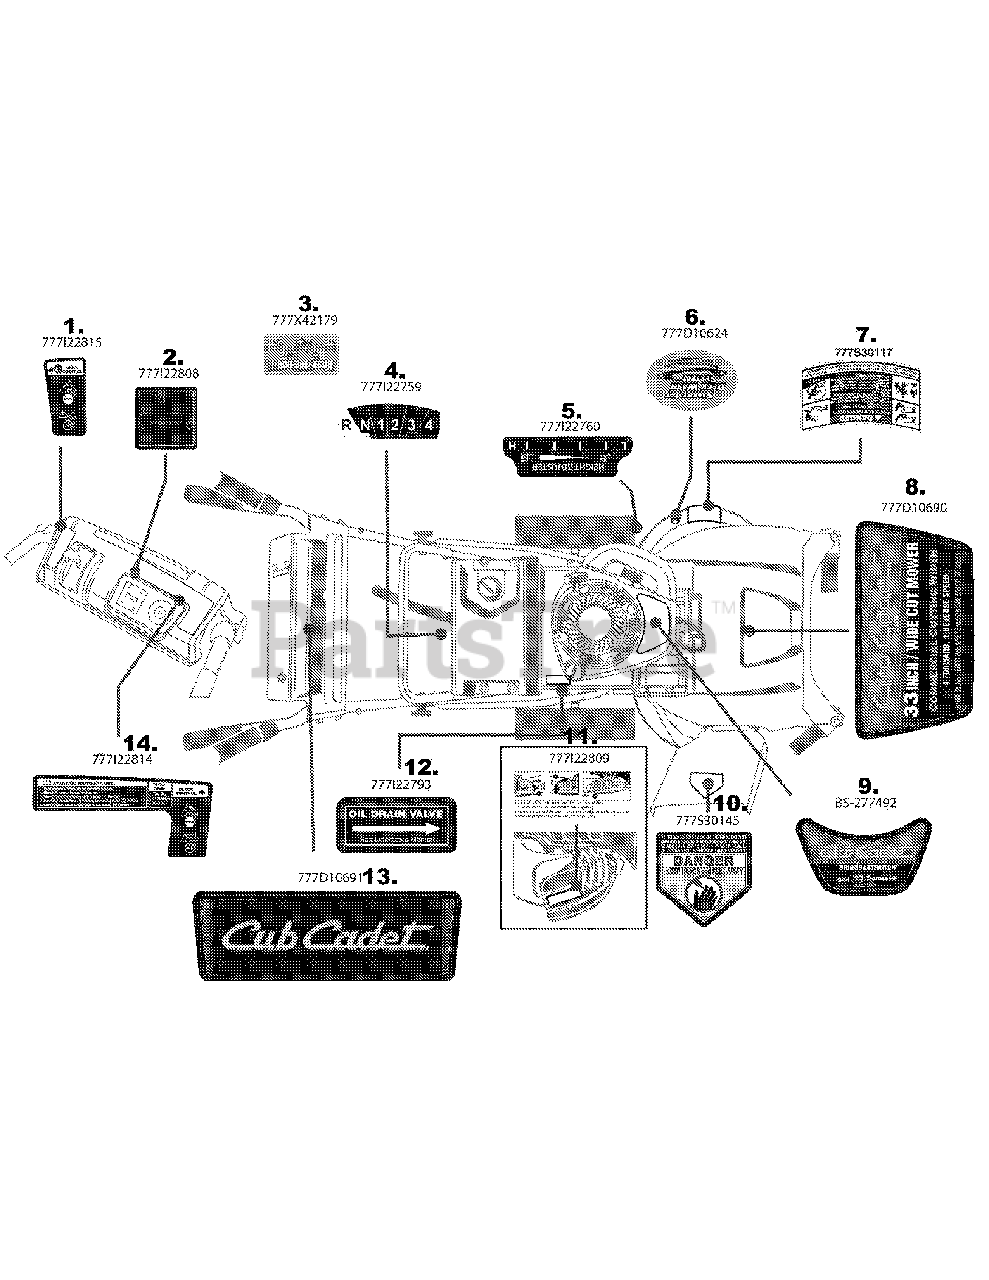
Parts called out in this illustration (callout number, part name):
1	LABEL-WIDECUT HANDLE LH
2	LABEL-HOUR METER
3	LABEL-CUB HOTLINE
4	LABEL-SPEED INDICATE
5	LABEL-HEIGHT ADJUST
6	LABEL-RIDER:DECK WASH CUB
7	LABEL-DANGER MWR DECK
8	LABEL-TIME SAVER 33"
9	LABEL-ENG SHROUD
10	LABEL
11	LABEL-MULCH PLUG
12	LABEL-OIL DRAIN VLV
13	LABEL-CUB CADET
14	LABEL-WIDECUT HANDLE RH
